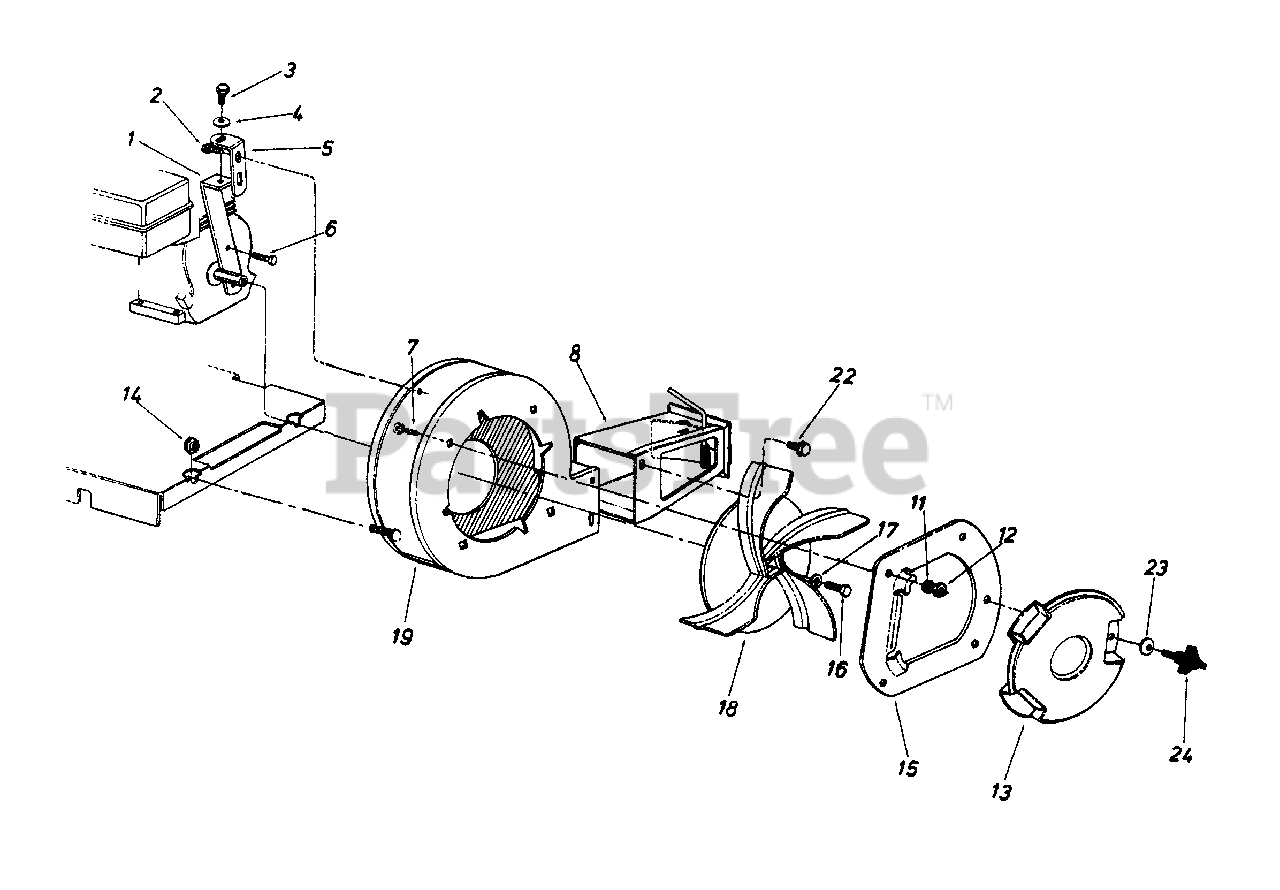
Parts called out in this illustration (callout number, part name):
3	Hex Bolt 5/16-18 x .75" Lg.
4	L-Wash. 5/16" I.D.
7	Carriage Bolt 5/16-18 x .62"
12	Hex Nut 5/16-18 Thd. (Gr. 5)
13	Blower Guard
14	Hex Shoulder Nut .50" I.D.
17	L-Wash. 3/8" I.D.-H.D.
23	Bell-Wash. .34" I.D. x .87" O.D.
24	3-Arm Thumb Scr. 5/16-18 x .75" Lg.
